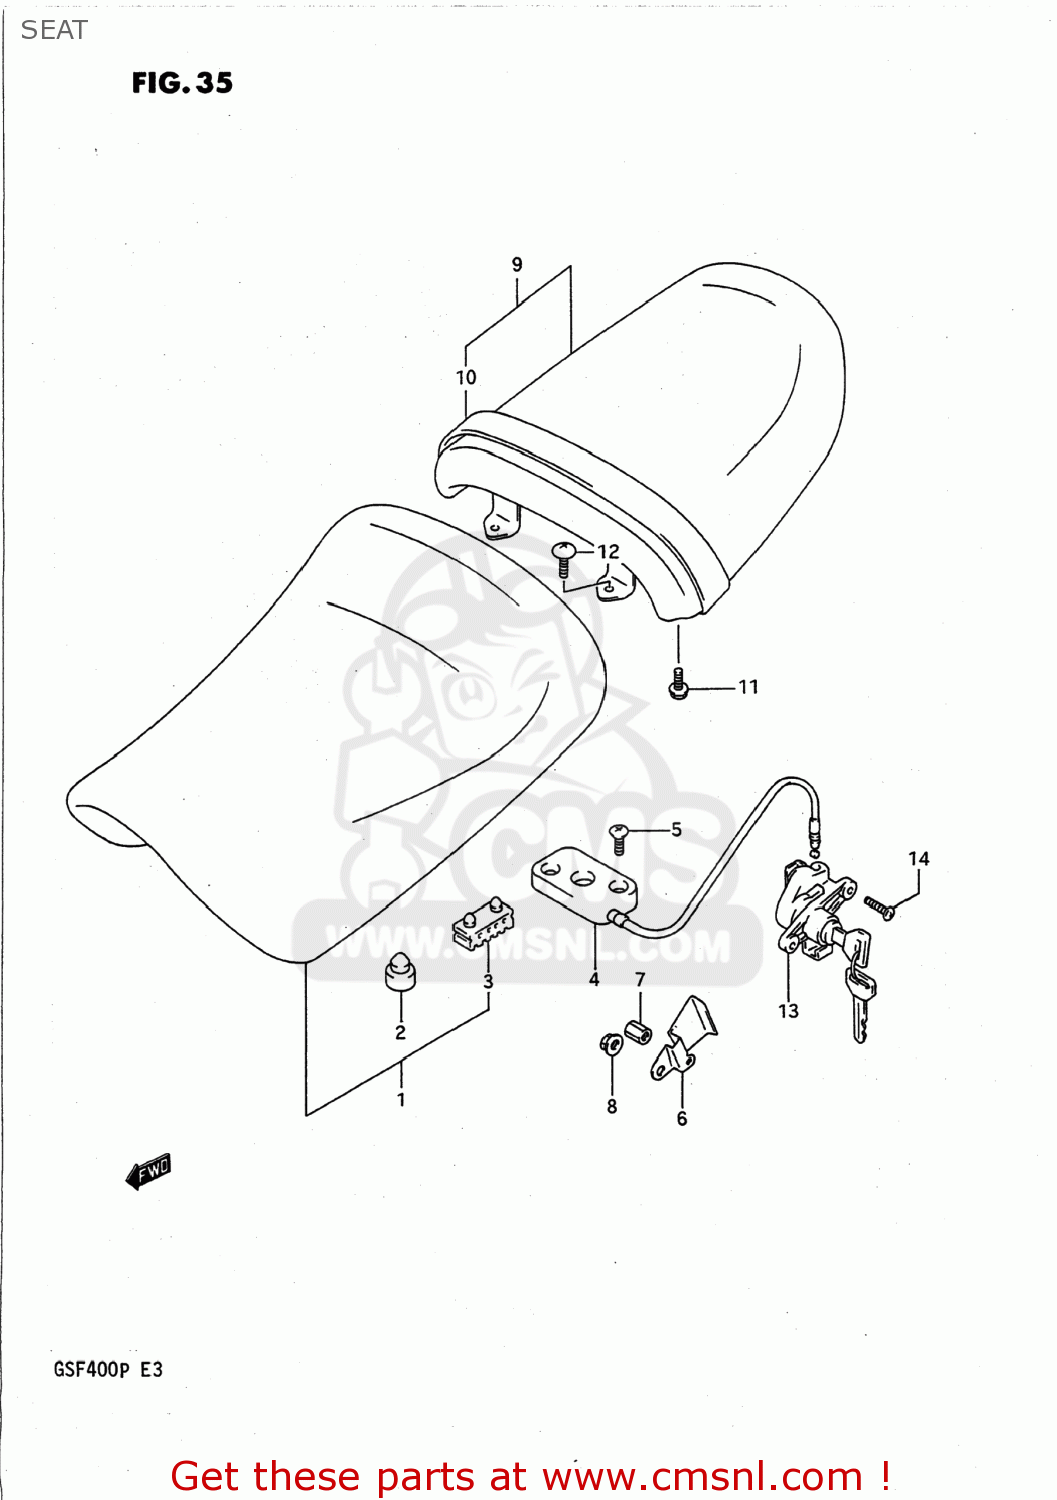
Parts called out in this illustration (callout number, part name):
1	SEAT ASSEMBLY
2	CUSHION
3	CUSHION,SEAT(40X20X15)
4	BRACKET,SEAT SUPPORT
5	SCREW
6	PLATE,SEAT LOCK CABLE
7	NUT
8	NUT
9	SEAT ASSY,PILLION
10	BAND,SEAT
11	BOLT
12	SCREW(6X12)
13	LOCK SET,SEAT & HELMET
14	SCREW(6X20)
